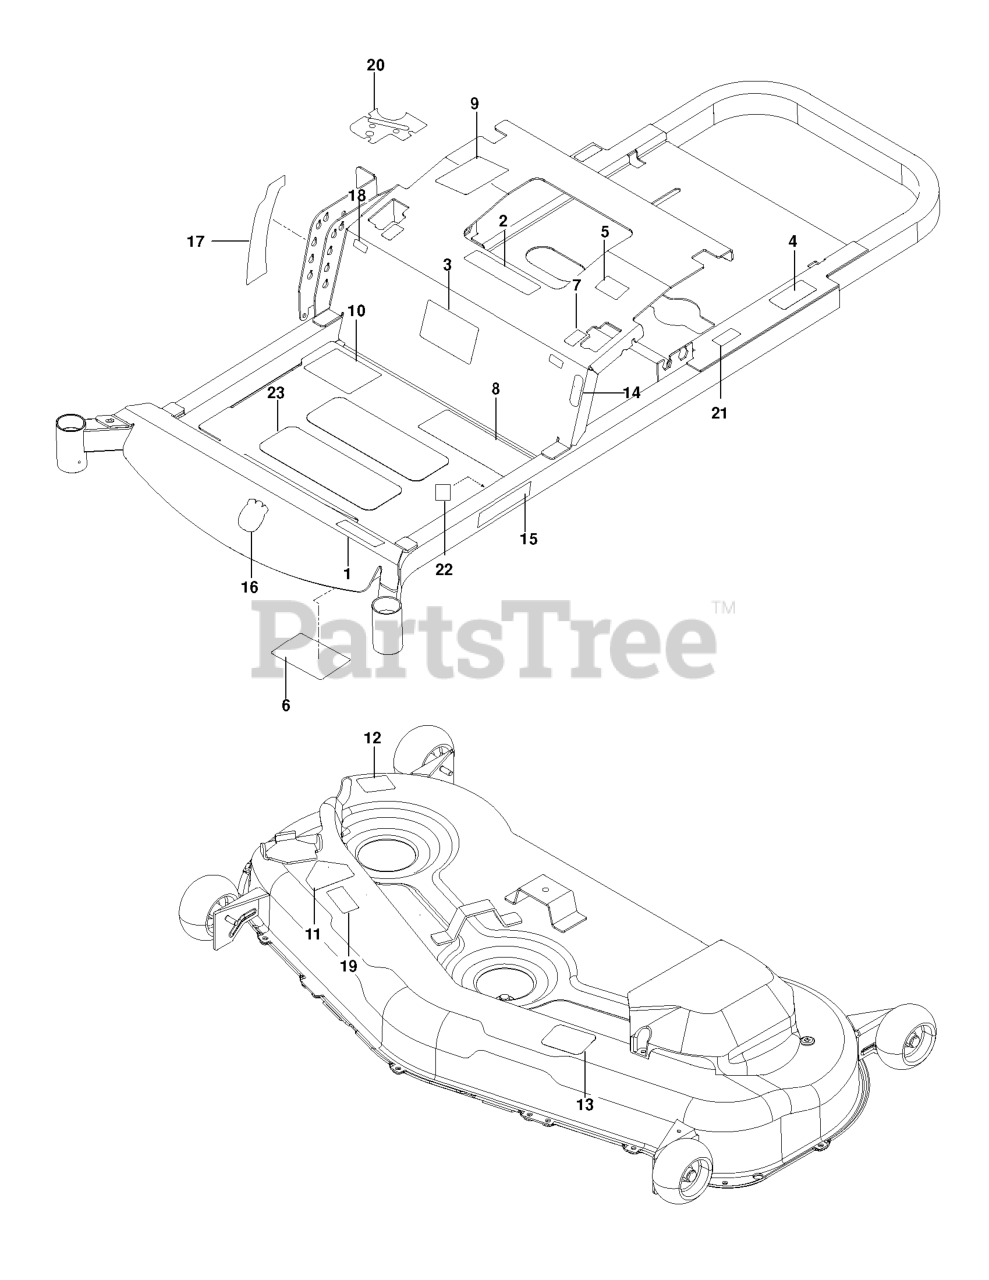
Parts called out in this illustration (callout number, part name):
1	DECAL.ZTR.RZ5424T.
2	EURO DECAL-BATTERY WARNIN6
3	DECAL, START
4	DECAL, DO NOT TOW
5	DECAL, EXITING MOWER
6	DECAL, SERVICE
7	DECAL, MOTION CONTROL
8	DECAL, SAFETY WARNING
9	DECAL, CUSTOMER RESPNSIBILITY
10	DECAL, WARNING
11	DECAL, CPSC
12	DECAL, CAUTION
13	DECAL, BELT ROUTING
14	DECAL, PARK BRAKE
15	RP.DECAL.BADGE.170MM.TEXTLOGO
16	DECAL.AUGER.HUSQ.CROWN.SNOW
17	DECAL, DECK HEIGHT, HUSQ
18	DECAL, F.S.T.
19	DECAL, EURO SEVERING
20	DECAL, CTRL PANEL, HUSQ
21	DECAL, ECM, AUSTRALIA
22	DECAL.80.DBA.AUSTRALIA
23	ANTI-SKID PAD
